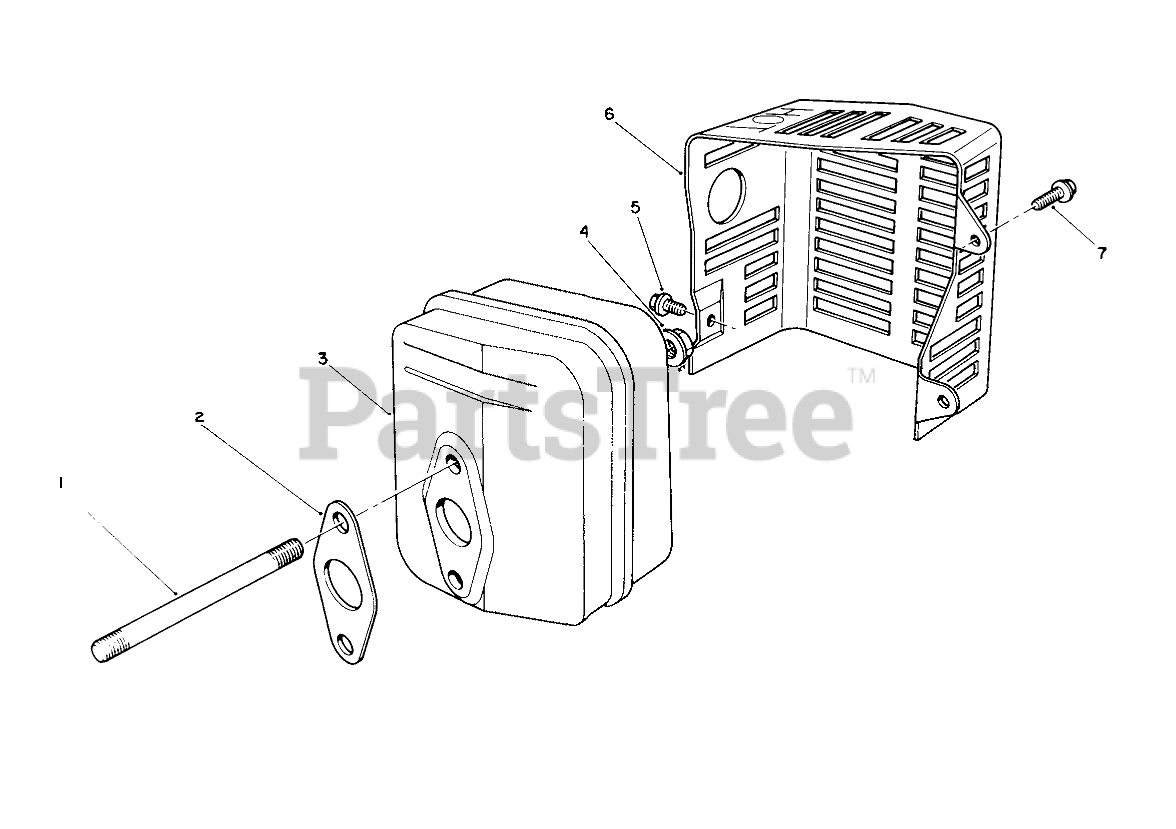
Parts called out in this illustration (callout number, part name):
2	GASKET
3	MUFFLER
5	SCREW
6	COVER
